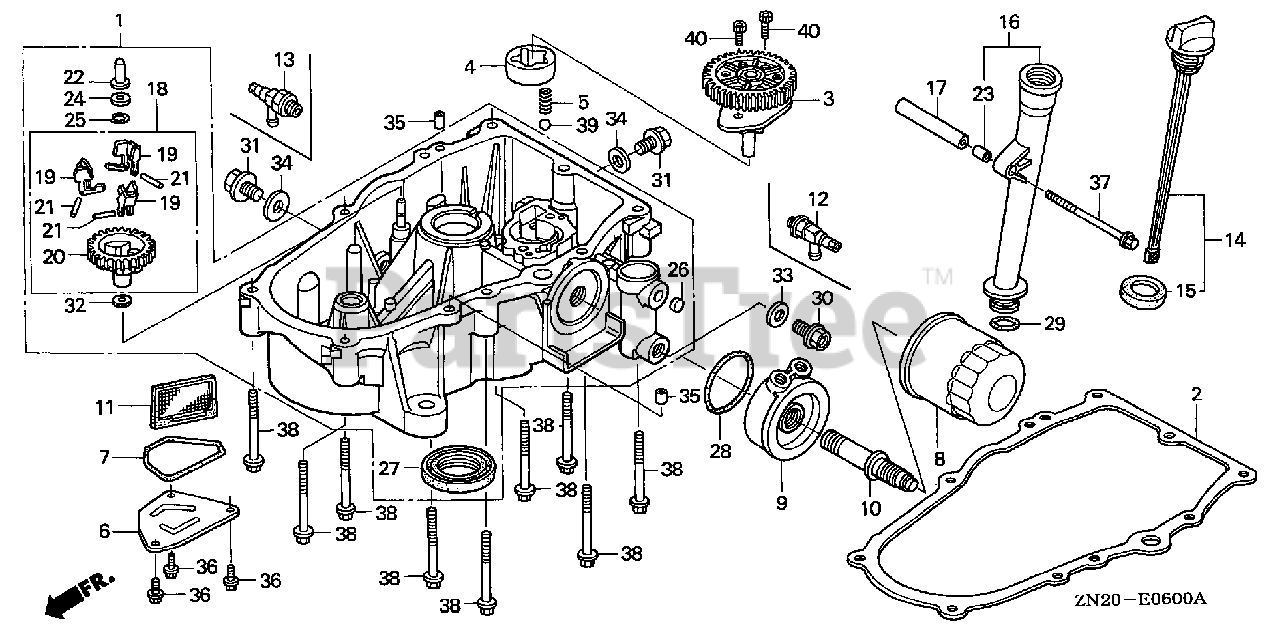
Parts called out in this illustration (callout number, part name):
1	PAN ASSY., OIL
2	GASKET, CASE COVER
3	COVER ASSY., OIL PUMP (TWO BOLTS)
3	COVER ASSY., OIL PUMP (THREE BOLTS)
4	ROTOR, OIL PUMP (OUTER)
5	SPRING, RELIEF VALVE
6	PLATE, OIL FILTER
7	O-RING, OIL PLATE
8	FILTER, OIL (FILTECH TOYO ROKI) (SOLD INDIVIDUALLY)
8	FILTER, OIL (TOYO ROKI) (SOLD INDIVIDUALLY)
9	BASE, OIL FILTER
10	BOLT, OIL FILTER
11	SCREEN, OIL FILTER
12	VALVE, DRAIN (14X1.5)
13	VALVE, OIL SHUT-OFF
14	CAP ASSY., OIL FILLER
15	GASKET, OIL FILLER CAP
16	EXTENSION, OIL FILLER
17	COLLAR, FILLER SETTING
18	GOVERNOR ASSY.
19	WEIGHT, GOVERNOR
20	HOLDER, GOVERNOR WEIGHT
21	PIN, GOVERNOR WEIGHT
22	SLIDER, GOVERNOR
23	COLLAR, EXTENSION
24	WASHER (6X16)
25	CLIP, GOVERNOR HOLDER
26	PLUG, SEALING (10MM)
27	OIL SEAL (38X58X9)
28	O-RING (51.6X2.3) (ARAI)
29	O-RING (22.1X2.2)
30	BOLT, DRAIN PLUG (14MM)
31	BOLT, DRAIN PLUG (20MM)
32	WASHER, PLAIN (6MM)
33	WASHER, DRAIN PLUG (14MM)
34	WASHER, DRAIN PLUG (20MM)
35	PIN, DOWEL (8X14)
36	BOLT, FLANGE (6X14)
37	BOLT, FLANGE (6X100)
38	BOLT, FLANGE (8X50)
39	BALL, STEEL (#12) (3/8)
40	BOLT, SOCKET (6X16)
